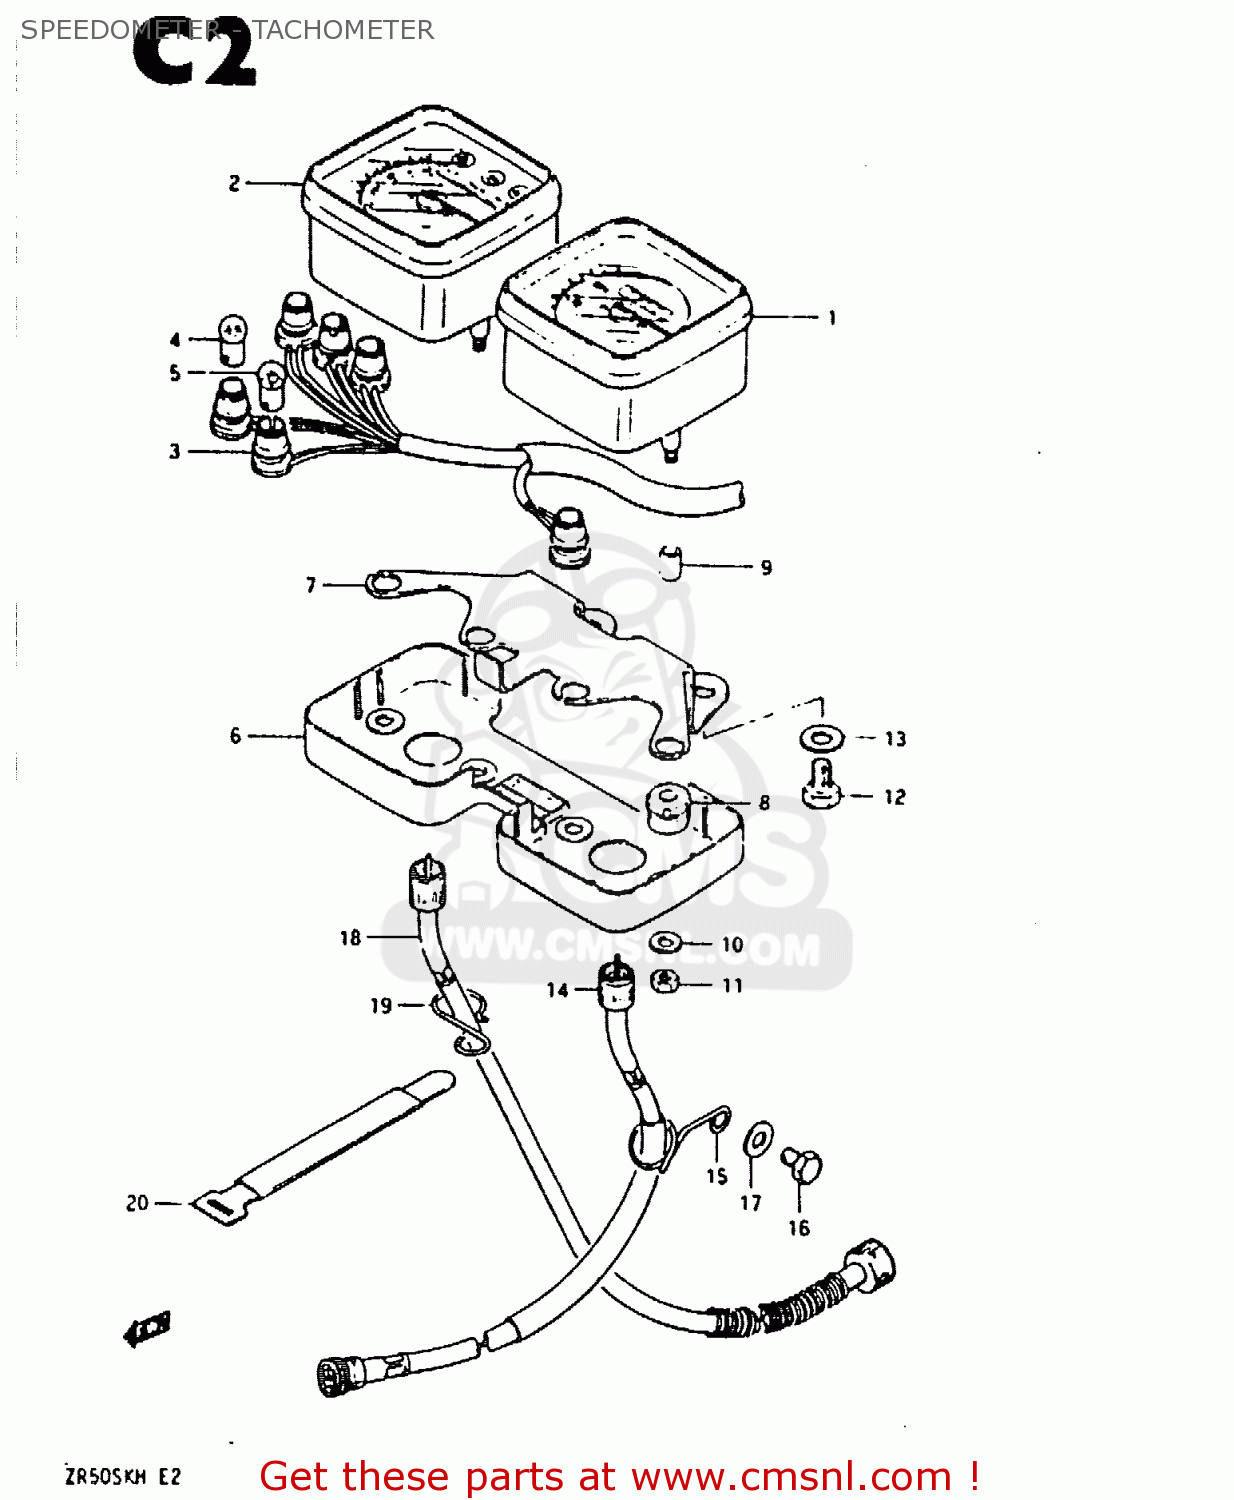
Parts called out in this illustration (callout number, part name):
1	SPEEDOMETER (KILO)
2	TACHOMETER
3	SOCKET
4	BULB(6V1.7W,STANLEY,A61A)
5	BULB(6V/3W)
6	COVER,METER UNDER
7	BRACKET
8	CUSHION,METER
9	SPACER
10	WASHER
11	NUT ,5MM
12	BOLT 8X12
13	WASHER
14	CABLE, SPEEDOMETER
15	CLIP
16	BOLT
17	WASHER
18	CABLE ASSY,TACHOMETER
19	CLIP,WIRING HARNESS
20	CLAMP
